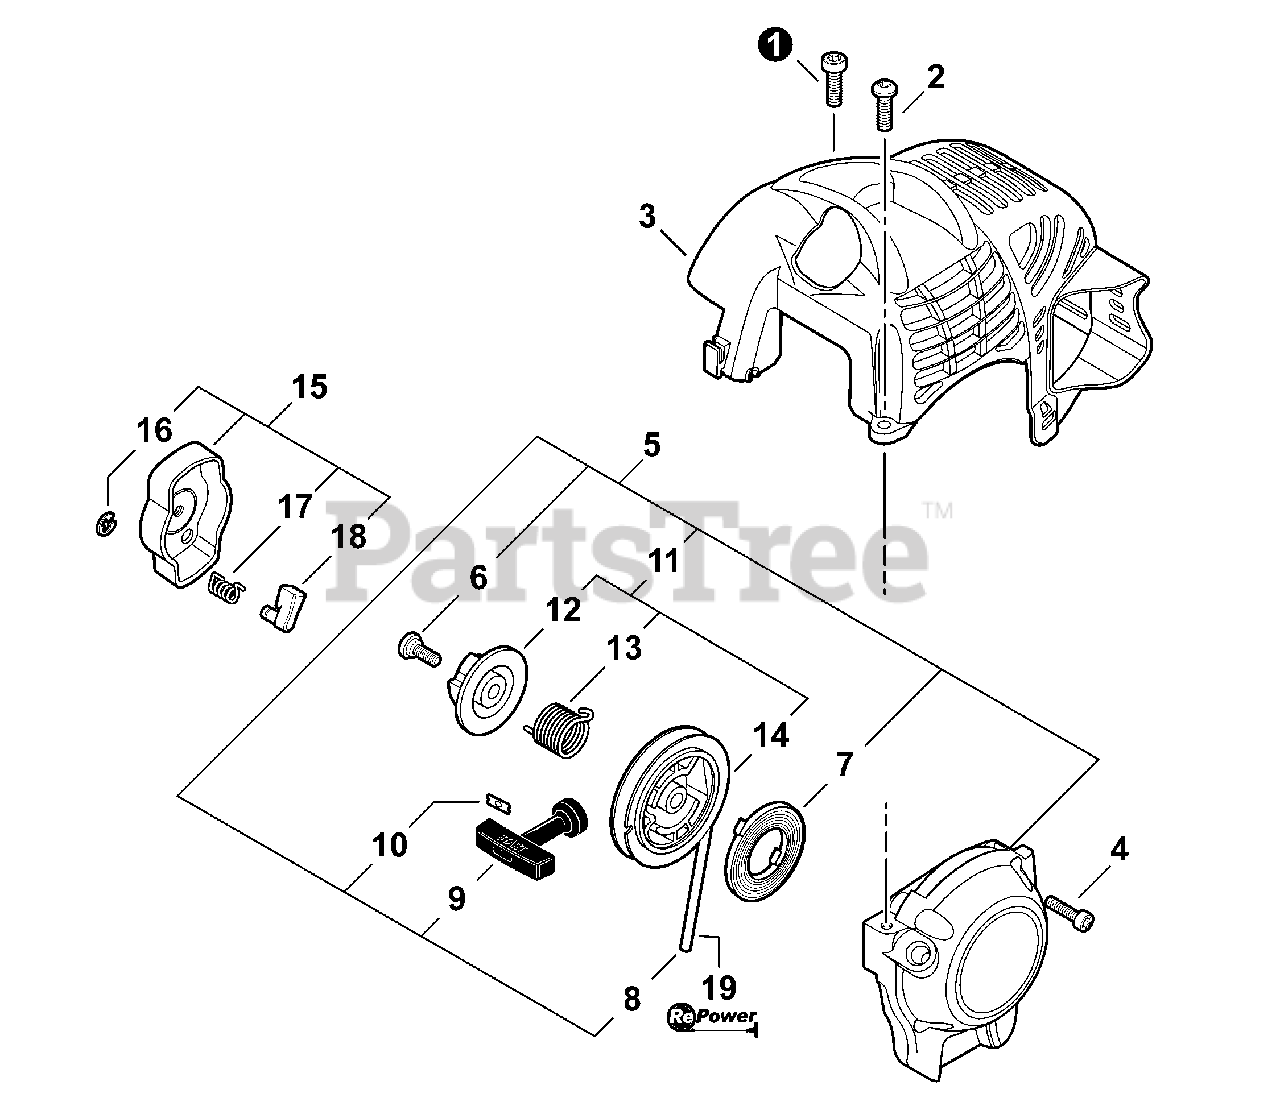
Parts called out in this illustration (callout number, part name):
1	BOLT, TORX 5×16
2	BOLT, TORX 5×16
3	COVER, ENGINE
4	BOLT, TORX 4×16
5	STARTER ASSY, RECOIL
6	SCREW
7	SPRING, RECOIL
8	ROPE, STARTER 3×700
9	GRIP, STARTER
10	RETAINER, ROPE
11	REEL/CAM PLATE SET
12	PLATE, CAM
13	SPRING, TORSION
14	REEL, ROPE
15	PAWL ASSY, STARTER
16	E-RING 4
17	SPRING, RETURN
18	PAWL, STARTER
